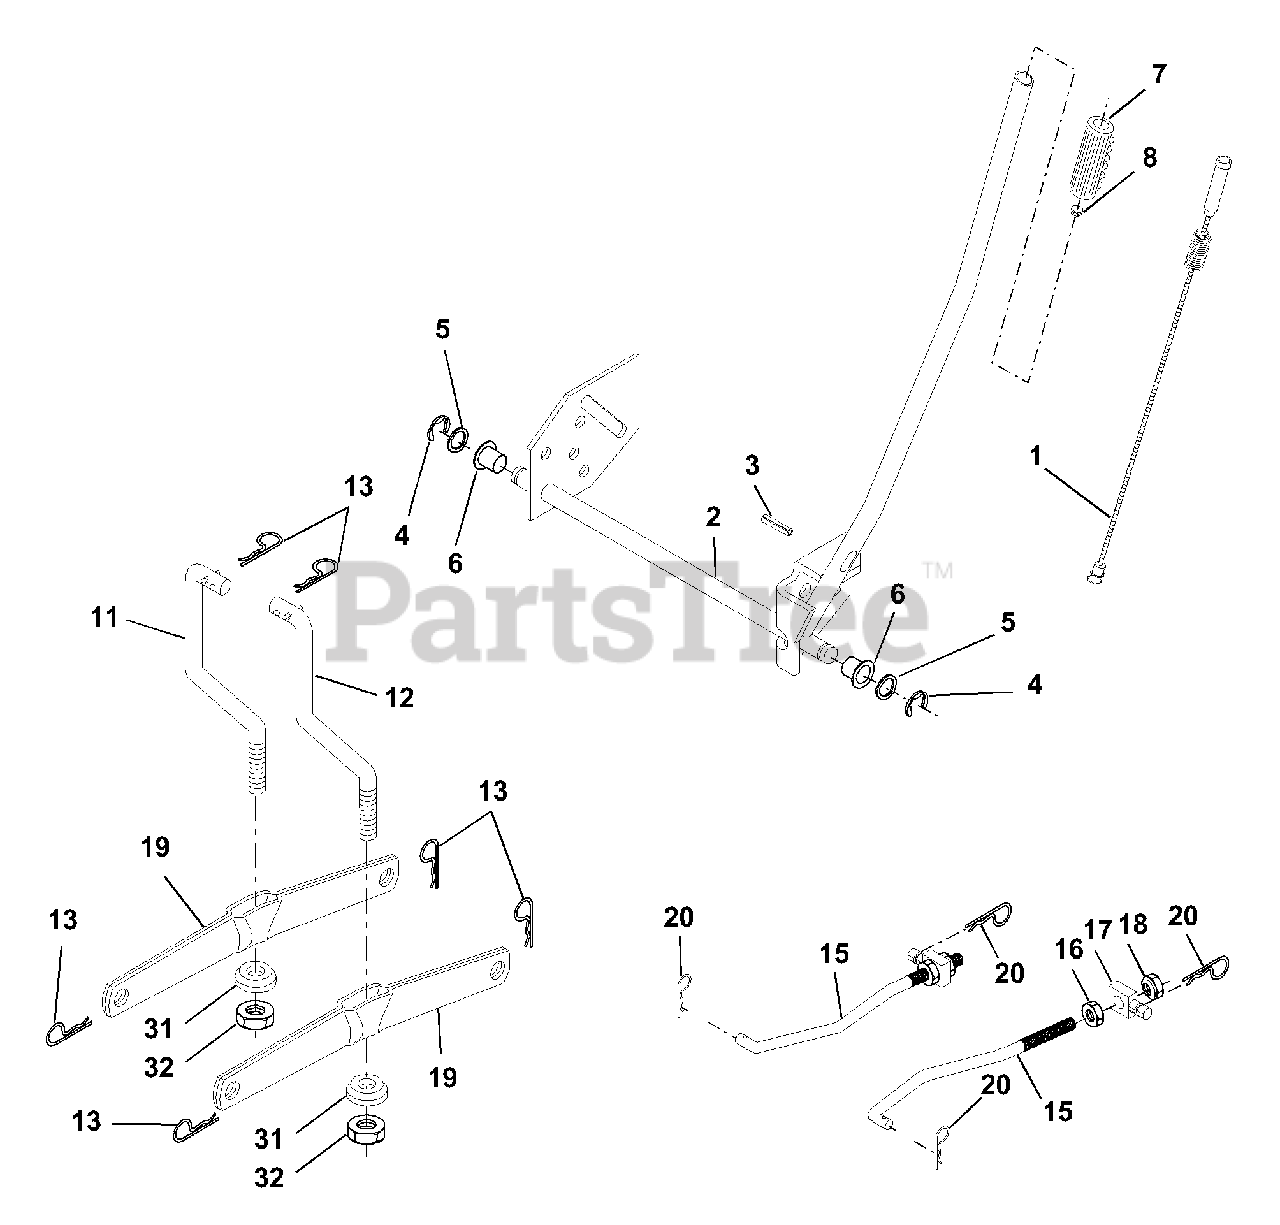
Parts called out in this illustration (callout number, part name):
1	Rod Asm. Lever
2	Shaft Asm. Lift
3	Pin Groove
4	E Ring #5133-62
5	Washer 21/32 x 1 x 21 Ga.
6	Bearing Nylong
7	Grip Handle
8	Button Plunger
11	Link Lift Lh
12	Link Lift Rh
13	Retainer Spring
15	Link Front
16	Nut Jam Hex 1/2-13 Unc
17	Trunnion Blk Zinc
18	Nut Crownlock 1/2-13 Unc
19	Arm Suspension Rear
20	Retainer Spring
31	Bearing
32	Nut Crownlock 3/8-24
